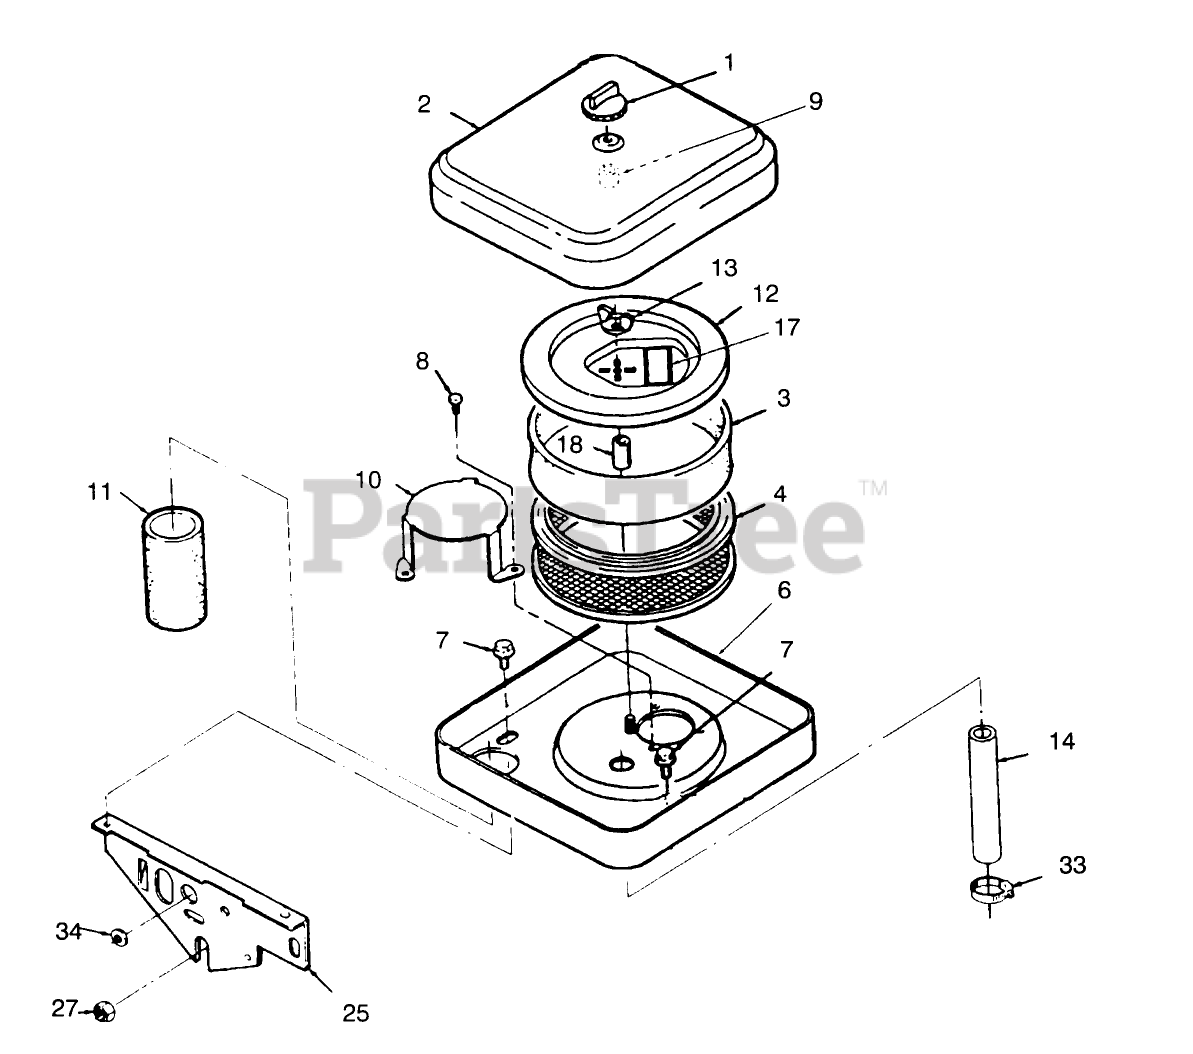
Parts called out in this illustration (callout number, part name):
1	KNOB-TOOL LESS
2	COVER - AIR CLEANER
3	WRAPPER-AIR CLEANER ELEMENT
4	ELEMENT-AIR CLEANER
6	HOUSING-AIR CLEANER
7	SCREW-TAPPING
8	MACHINE SCREW
9	SCREW-TAPPING
10	PLATE-AIR DEFLECTOR
11	TUBE-AIR INTAKE
12	ELEMENT COVER KIT
13	1/4-20 WING NUT
14	HOSE-BREATHER
17	DECAL-PERIODIC MAINTENANCE
18	SPACER-AIR CLEANER STUD
25	SUPPORT-AIR CLEANER
33	CLAMP-HOSE, BREATHER
34	GROMMET
